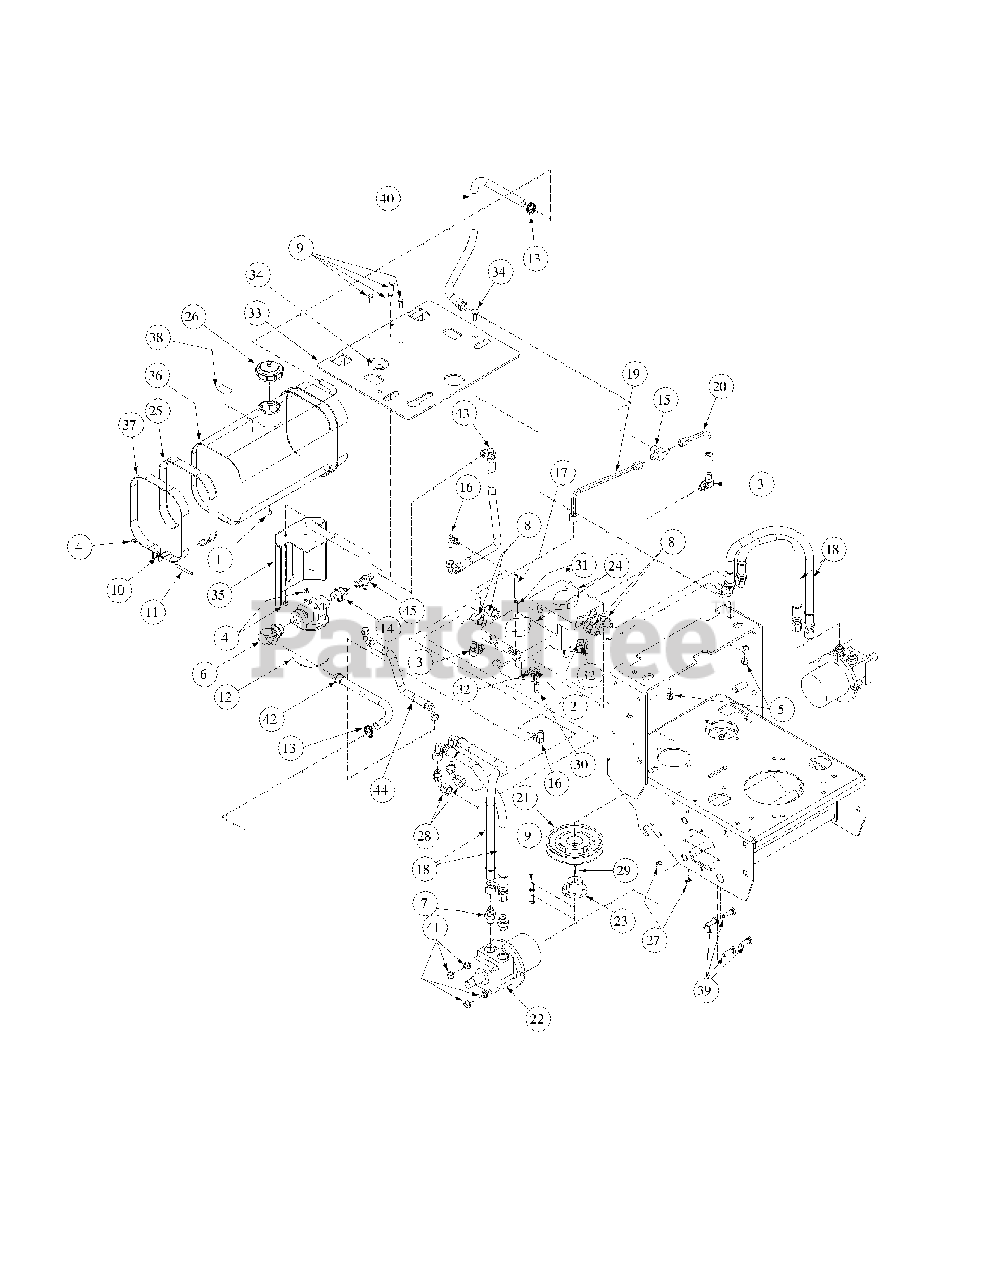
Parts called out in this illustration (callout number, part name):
1	Plug, 1/4"
2	Cap Screw, Standard, 3/8-16 x 1-1/4
3	Fitting, Aeroquip
4	Lock Nut, 1/4-20
5	Lock Nut, 3/8-16
6	Elbow 90° 1/2 x 3/4
7	Fitting, Aeroquip
8	Fitting, Aeroquip
9	Cap Screw, 1/4-20 x 3/4
10	Hex Nut, 1/4-20
11	Machine Screw, 1/4-20 x 2, Zinc
12	Filter Head 3/4
12	Oil Filter
13	Clamp Wormgear, 5/16-7/8
14	Straight Connector 1/2 x 3/4
15	Fitting Aeroquip
16	Fitting, Aeroquip
17	Cap Screw, Socket Head, 1/4-20 x 2-1/2 Zinc
18	Hydro Hose Assembly, Reverse Pressure
19	Hydraulic Line, Pump Return Long
20	Hydraulic Line, Pump Return Short
21	Deck Pulley
22	Hydraulic Motor, Wheel
23	Bushing, 15mm Bore, Split, Type "D"
24	Pump Hydro BDP10L117
25	Pad, Oil Tank
26	Cap, Hydraulic Oil Tank
27	Lock Nut, 3/8-16
28	Fitting Aeorquip
29	Pump Key
30	Nut, Pump Release
31	Spacer, Pump Release
32	Washer, Idler
33	Fuel Tank, Mounting Plate
34	Carriage Bolt, 3/8-16 x 2
35	Filter Guard
36	Oil Tank w/Neck
37	Oil Tank Strap
38	Oil Label, 20W-50
39	Carriage Bolt, 3/8-16 x 1.25
40	Hose Assembly
40	Hose Hydraulic 22"
41	Hex Nut, Flange Lock, 3/8-16
42	Hose, Filter to Tank
43	Hose, Filter to Left Pump
44	Hose, Filter to Right Pump
45	Fitting, Aeroquips
